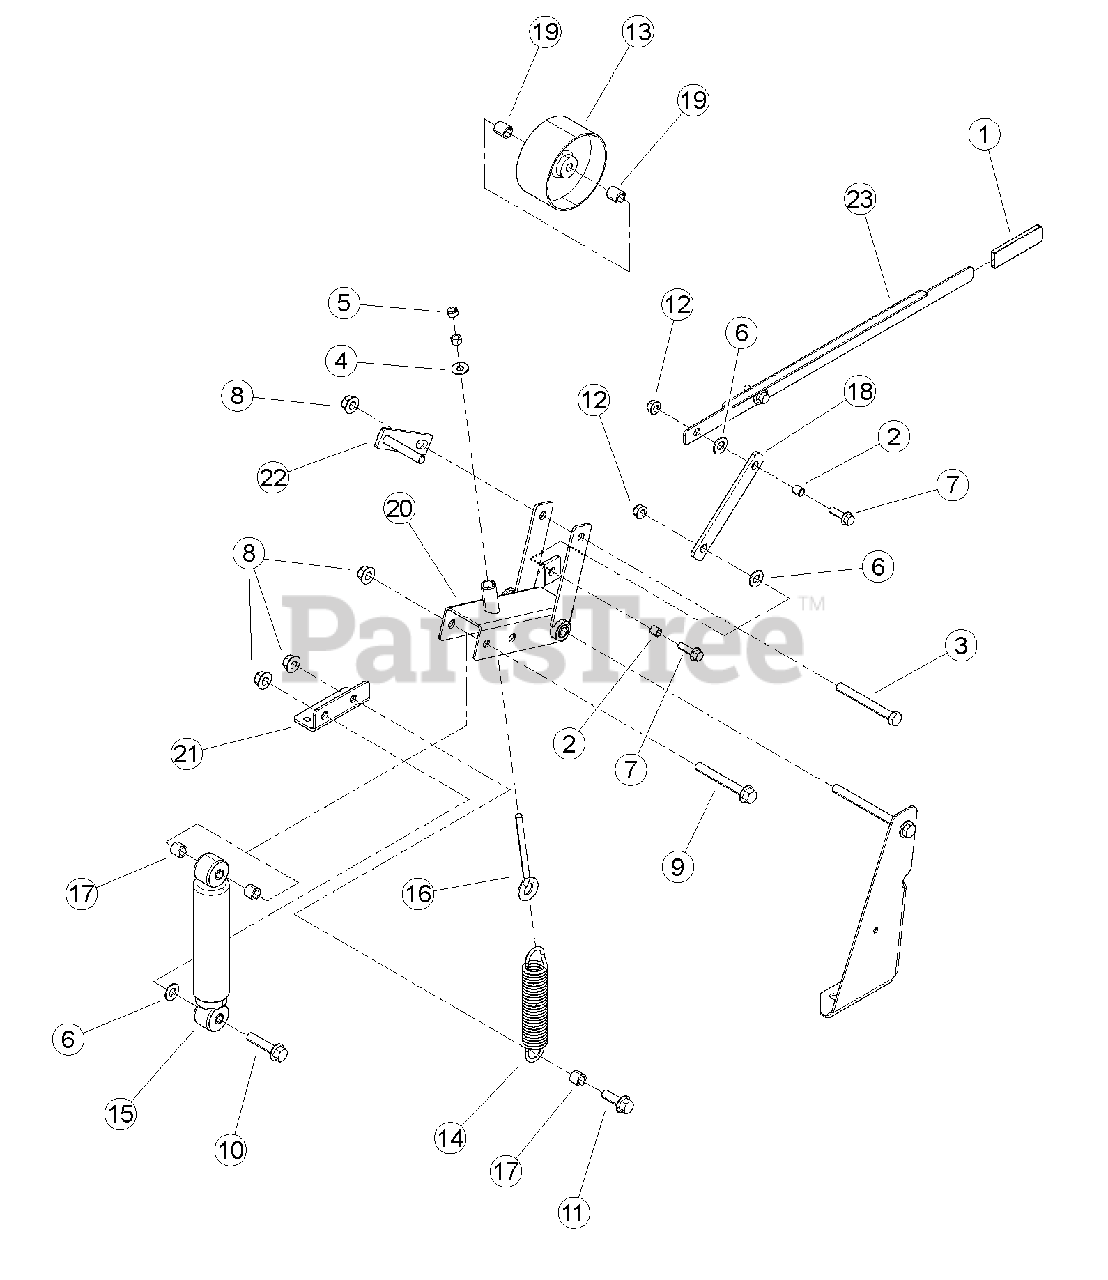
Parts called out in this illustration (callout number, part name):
1	GRIP, CLUTCH HANDLE
2	BUSHING, 3/8 X 1/2 SLEEVE LUBE
3	BOLT, 1/2 X 4-1/2" GR5 HHCS NC ZP
4	WASHER, 3/8" FLAT ZP
5	WASHER, 1/2" FLAT ZP
6	NUT, 3/8" HEX NC ZP
7	WASHER, 1/2" SAE FLAT ZP
8	BOLT, 3/8 X 1-1/4 FLANGE NC
9	NUT, 1/2-13 NYLOCK FLANGE
10	BOLT, 1/2-13 X 4 HWH GR5 CZP
11	BOLT, 1/2 -13 X 2-1/4 FLANGE NC
12	BOLT, 1/2-13 X 1-1/2 GR5 FLANGE NC
13	NUT, 3/8-16 NYLOCK FLANGE
14	PULLEY, IDLER 5 X 2.50"
15	SPRING, 7-3/4" EXTENSION
16	ABSORBER, IDLER SHOCK
17	EYEBOLT, 3/8 X 5" LG 4-1/4THD ZP
18	SPACER, 0.75 X 0.620
19	LINK, ENGAGEMENT ARM
20	SPACER, IDLER SHEAVE
21	WELDMENT, IDLER ARM
22	BRACKET, SPRING ANCHOR
23	WELDMENT, BELT PIN
24	BUSHING, IDLER PIVOT
25	LEVER, CLUTCH ENGAGEMENT
